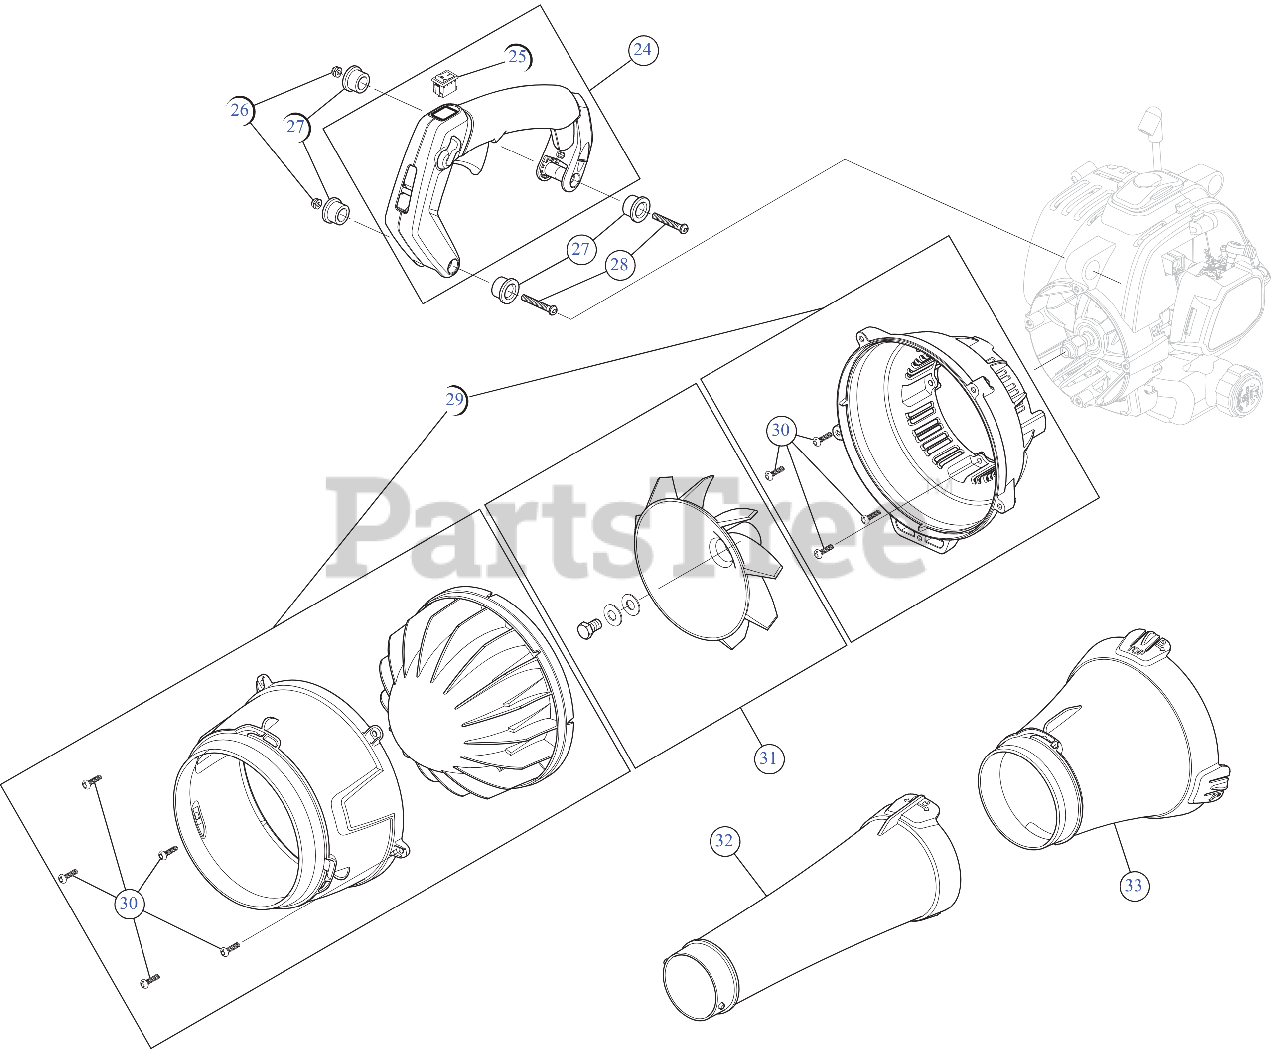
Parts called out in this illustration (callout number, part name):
24	HANDLE ASSEMBLY BLOWER
25	SW, MOMENTARY ON/O
26	HEX NUT
27	ISOLATOR MNT GRIP
28	SCREW
29	FAN ASSEMBLY HOUSING FR/RR
30	SCREW 8-16 x 3/4
31	FAN ASSEMBLY BLOWER
32	LOWER BLOWER TUBE
33	UPPER BLOWER TUBE
